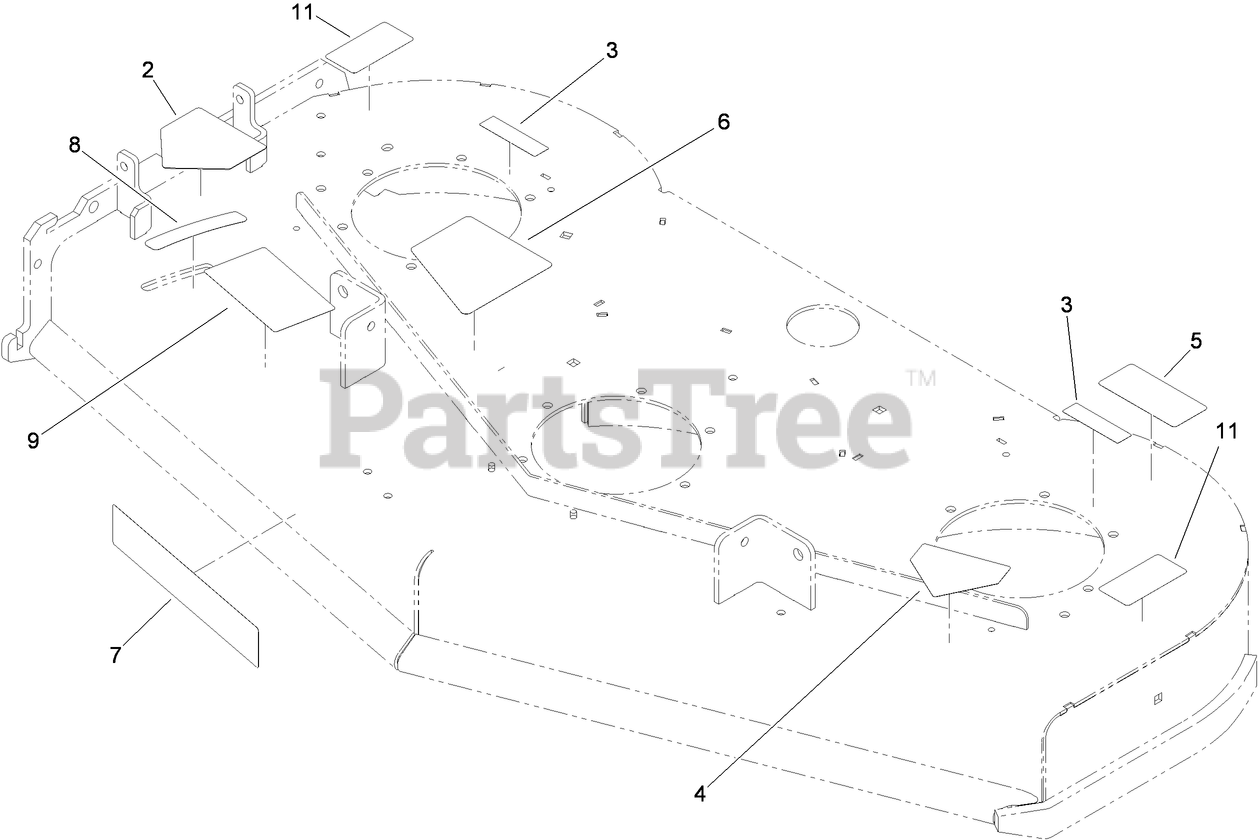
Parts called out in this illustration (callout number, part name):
2	DECAL-DANGER
3	DECAL-COVER, MISSING
4	DECAL-DANGER
5	DECAL-TORQUE
6	DECAL-TENSION, BELT
8	DECAL-SETTING, BAFFLE
9	DECAL-ADJUSTMENT, BAFFLE
11	DECAL-ROTATING PARTS
